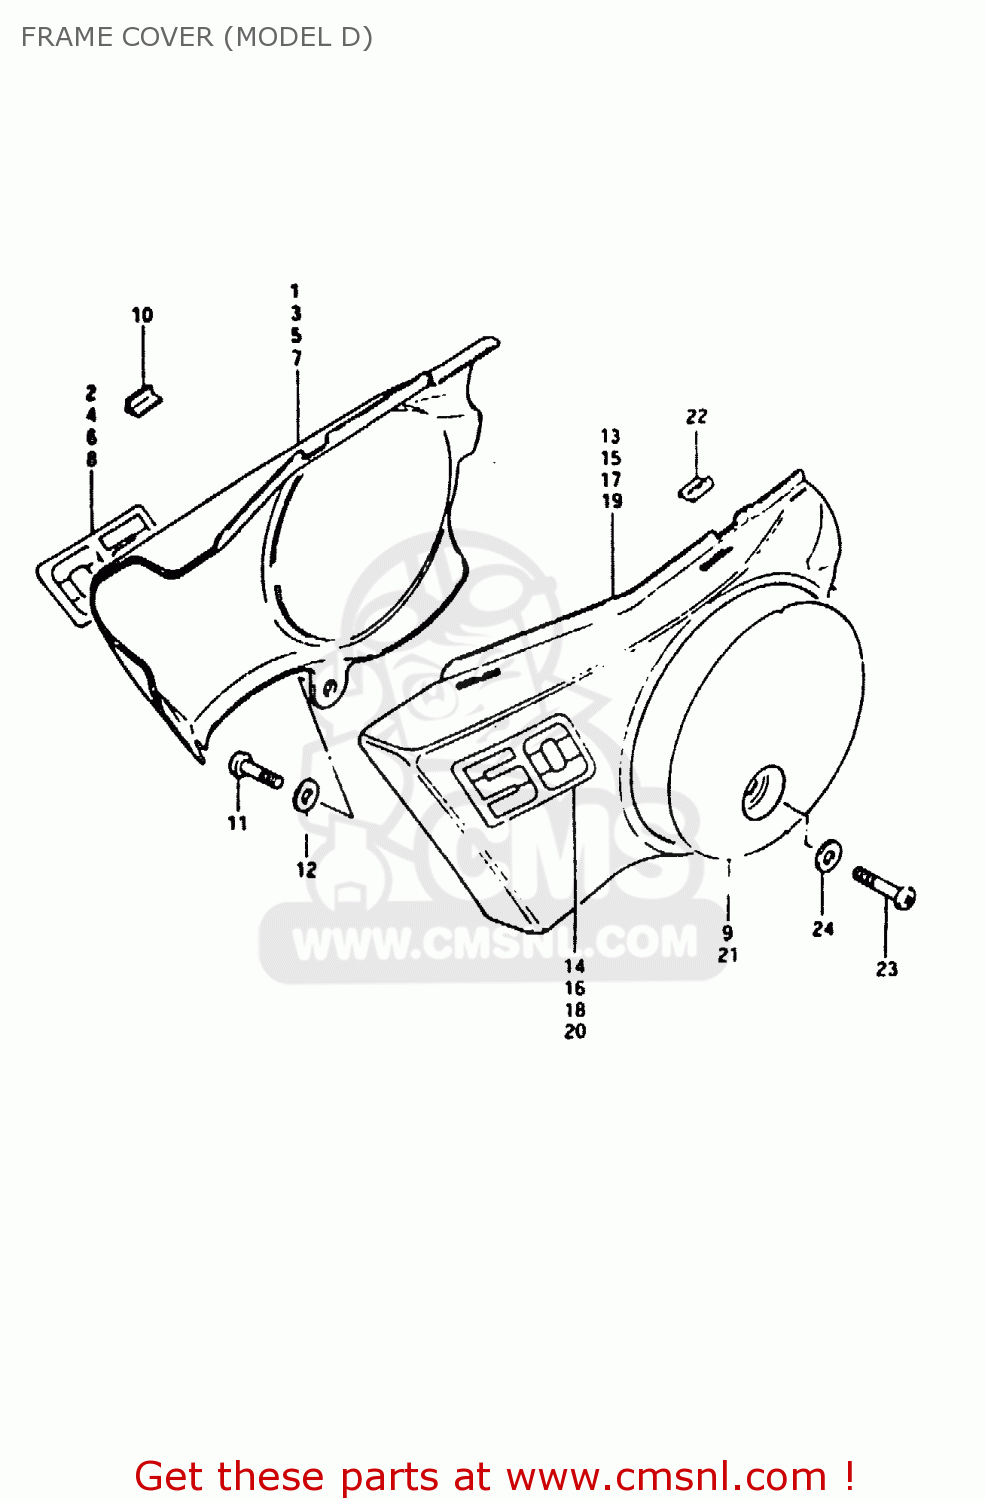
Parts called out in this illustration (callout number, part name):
1	COVER, FRAME RH (RED)
2	EMBLEM, RH
3	COVER, FRAME RH (BLACK)
4	EMBLEM, RH
5	COVER,FRAME RH
6	EMBLEM, RH
7	COVER,FRAME RH
8	EMBLEM, RH
9	EMBLEM, RH
10	CUSHION,FRAME COVER
11	SCREW
12	WASHER
13	COVER, FRAME LH (RED)
14	EMBLEM, LH
15	COVER, FRAME LH (BLACK)
16	EMBLEM, LH
17	COVER, FRAME LH (BLUE)
18	TAPE, LH
19	COVER, FRAME LH (YELLW)
20	TAPE, LH
21	EMBLEM, LH
22	CUSHION,FRAME COVER
23	SCREW
24	WASHER
